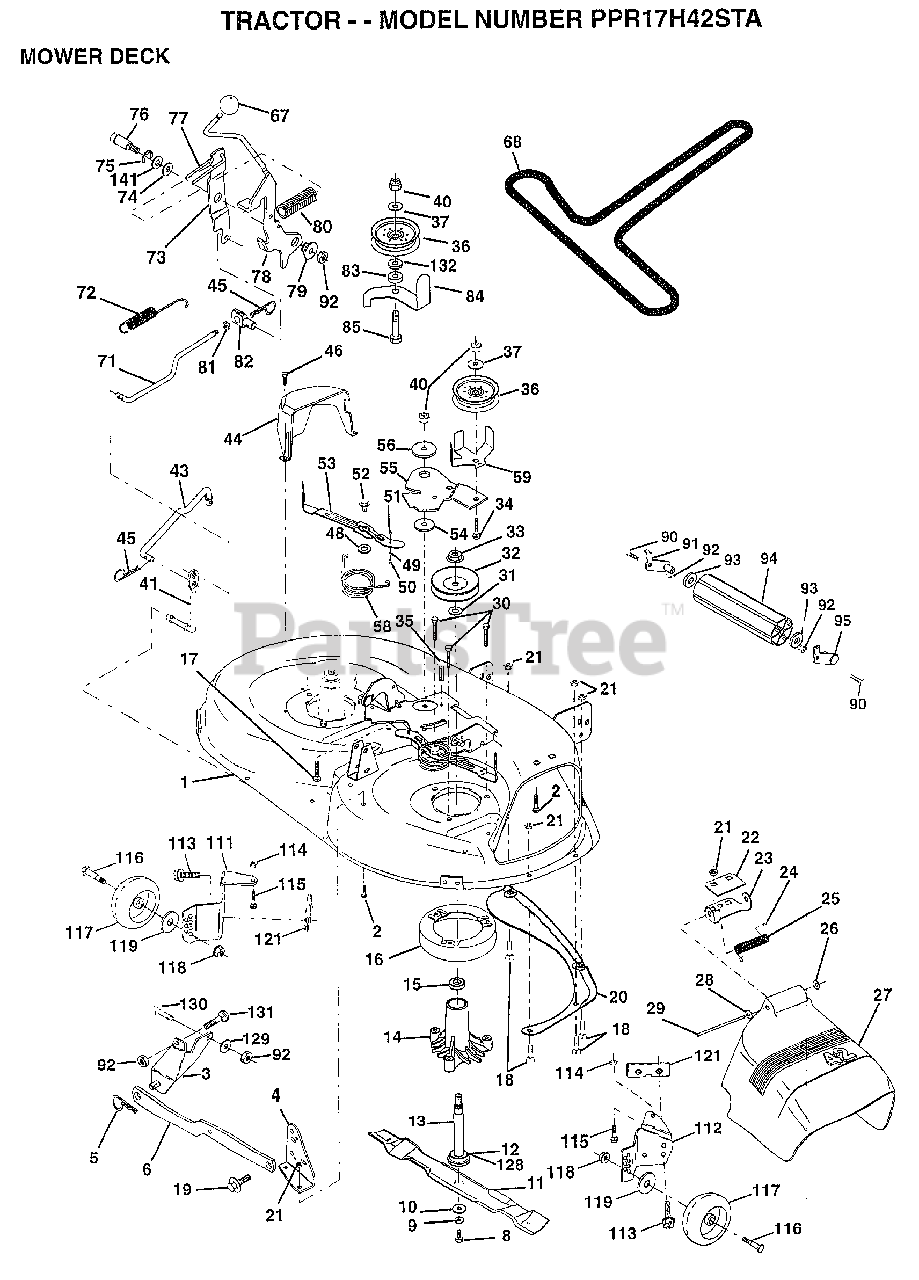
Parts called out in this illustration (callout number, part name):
1	"HOUSING ASSY.42"""
2	BOLT
3	BRKT ASM SWAY BAR
4	BRKT DECK SW BAR
8	BLADE BOLT
10	WASHER.HARD.BLADE
11	"BLADE.42"" HIPERF"
12	BEARING.BALL
14	HSG ASM MANDREL
15	BEARING
16	STRIPPER RND MWR
17	BOLT RDHD 3/8-16
18	BOLT
19	BOLT SHD 5/16-18
20	BAFFLE VORTEX 42
22	STIFFENER BRKT
23	DEFLECTOR BRKT
24	CAP-SLEEVE LT
25	SPRING TORSION
26	NUT PUSH M
27	DEFLECTOR.SHIELD
28	WASHER
29	HINGE ROD
30	"SCREW-THD ROLL,WA"
31	WASHER
32	PULLEY.MANDREL.42
34	BOLT
35	XMAS TREE FASTNER
36	FLAT IDLER PULLEY
37	WASHER
41	PIVOT ROD
43	ROD CLUTCH W/NIBS
44	GUARD MAND LH BLK
45	RETAINER M
46	SCREW.1/4-20X5/8
48	HARD SMALL WASHER
49	ROLLER ASM-CAM
50	SHOULDER BOLT
51	LOCKNUT
52	BOLT.SHLD.5/16-18
53	BRAKE PAD ARM ASM
54	HARDENED WASHER
55	ARM-IDLER
56	SPACER RETAINER
58	SPRING TORSN BRAK
59	GUARD IDLER TUV
67	KNOB.RD.7/16-14
68	BELT.V.T-PATH
71	ROD CLUTCH 38/42
72	RETURN SPRING
73	CLUTCH ARM SECOND
74	WASHER
75	RING
76	SHOULDER BOLT
77	SPRING KEEPER
78	LEVER.ASM.CLUTCH
79	BUSHING
80	SPRING.CLUTCH.MWR
81	TRUNION ADJ
82	NUT
83	WASHER
84	"KEEPER-BELT,FIXED"
85	BOLT
90	BOLT
92	NUT
93	WASHER
111	BRACKET.GWHL.LH.
112	BRACKET.GWHL.RH.
113	SCREW
116	BOLT M
117	WHEEL.GUAGE
118	LOCKNUT
119	WASHER
121	BRACKET.EXTRD.GWL
128	WASHER.FELT.
129	WASHER
130	BOLT
132	WASHER GT
141	WASHER .T
